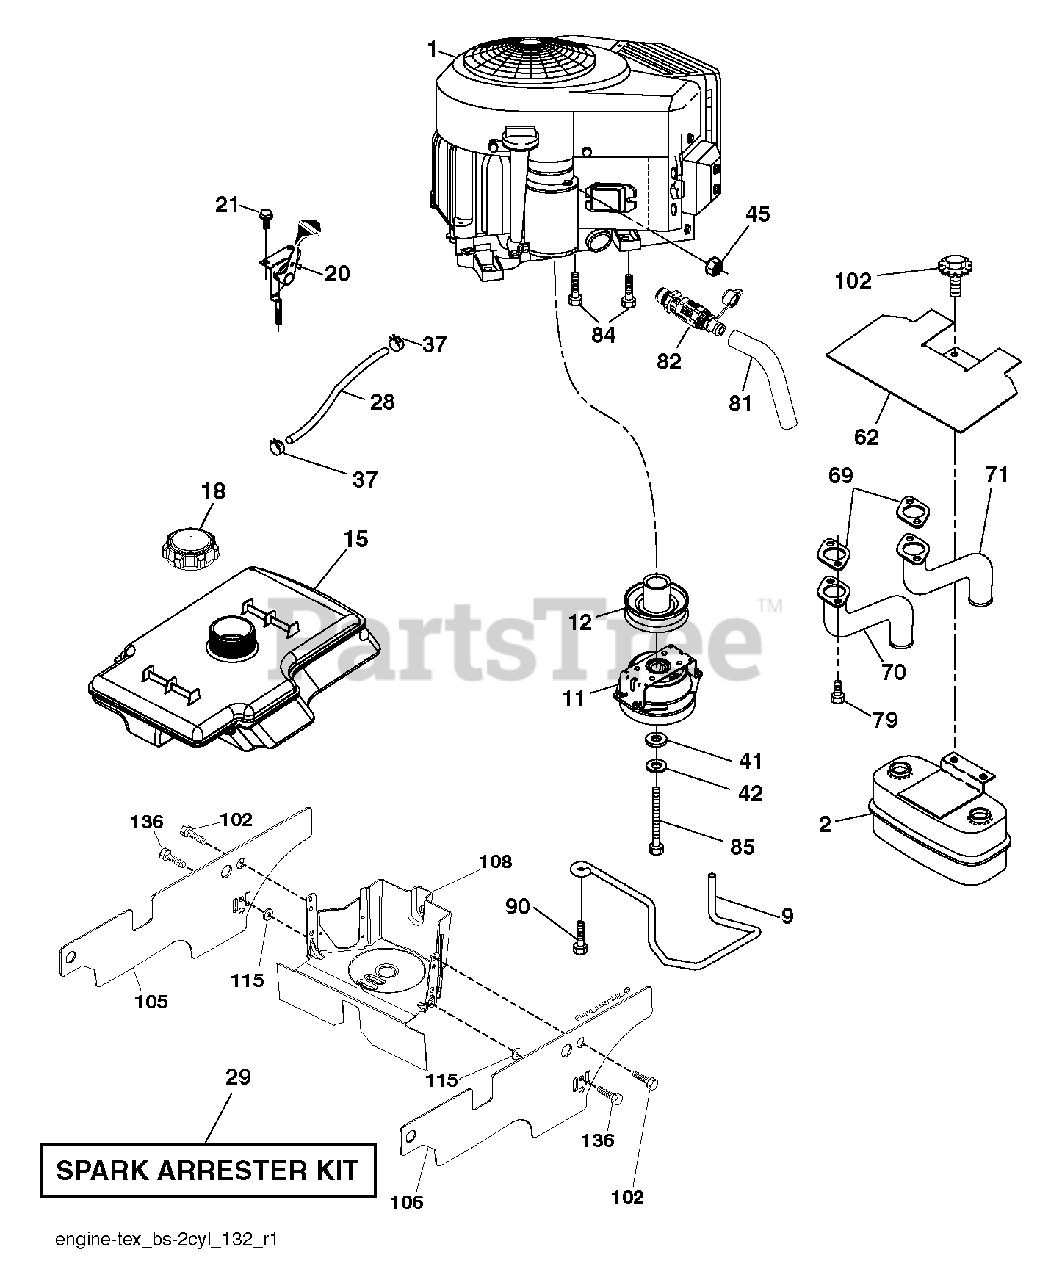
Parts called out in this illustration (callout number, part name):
2	MUFFLER.ASM.TWN.EXTNDED.DFLCTR
9	KEEPER BELT ENGINE
11	CLUTCH.OGURA.4.4PD.GT1.5-EH13V
12	PULLEY.ENGINE.TUFFTORQ
15	FUEL TANK
18	CAP.ASSY.FUEL.3".N-EPA.BLK.428
20	THROTTLE.COBRA.38"READSTART.BK
21	SCREW.#10 X 0.750.BOS
28	REPL BY 532 00 85-43
29	KIT.SPARK ARRESTOR 794945 B&S
37	HOSE CLAMP
42	LOCKWASHER
45	NUT
62	SHIELD.HEAT.MUFFLER
69	GASKET.MUFFLER
70	EXHAUST.TUBE.LH.BS/TWIN
71	EXHAUST.TUBE.RH.B&S.TWIN.INTEK
79	SCREW.SOCKET.HEAD.5/16-18
81	TUBE, DRAIN OIL ASM.
82	VALUE.OIL.DRAIN
84	SCREW.3/8-16
85	CLUTCH BOLT7/16-20X3.5 GR524HR
90	SCREW 3/8-16X1
102	SCREW
105	SHIELD.SIDE.LH.3842"TEX FRENCH
106	SHIELD.SIDE.RH.3842"TEX FRENCH
108	ENGINE COVER
115	PALNUT 1/4
136	SCREW.1/4-20X5/8
